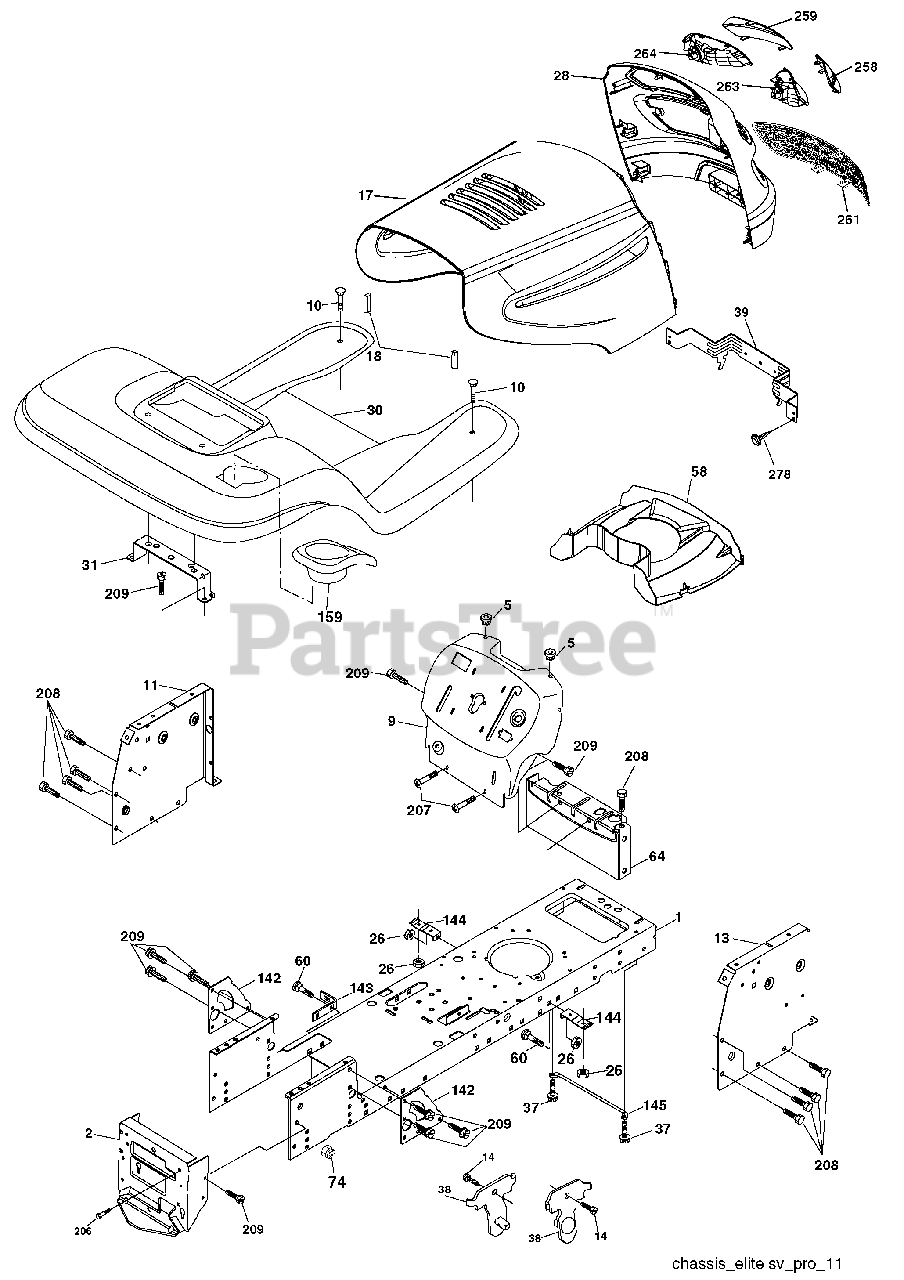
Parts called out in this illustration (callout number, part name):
1	Chassis
2	Drawbar
5	Bumper Hood/Dash
9	Dash P/L
10	Bolt Carriage 3/8-16 x 1
11	Panel Dash LH
14	Screw THDROL 3/8-16 x 1/2
17	Hood
18	Bumper Hood
26	Nut Lock Hex w/Ins 3/8-16 unc
28	Grille/Lens Asm
31	Bracket Fender
37	Screw Thdrol 6/16-18 x 1/2 TYT
38	Bracket Asm Pivot Mower Rear
39	Bracket Pivot
58	Duct Air
60	Bolt RDHD SQNK 3/8-16 unc x 1
64	Dash Lower STLT
74	Nut Crownlock 3/8-16 unc
142	Plate Reinforcement STLT
143	Bracket Swaybar Chassis
144	Bracket Footrest
145	Rod Pivot Chassis/Hood
159	Cupholder
206	Bolt Shoulder 5/16-18
207	Screw Thdrol 5/16-18 x 1/2
208	Screw Thdrol 3/8-16 x 1/2
209	Screw Hexwsh Thdr 3/8-16 x 3/4
258	Lens Grille Pro RH
259	Lens Grille Pro LH
263	Bezel Grille RH
264	Bezel Grille LH
278	Screw #10 x 0.750 BOS Thread
278	Plug BTN BlK
278	Plug Domed Plastic
